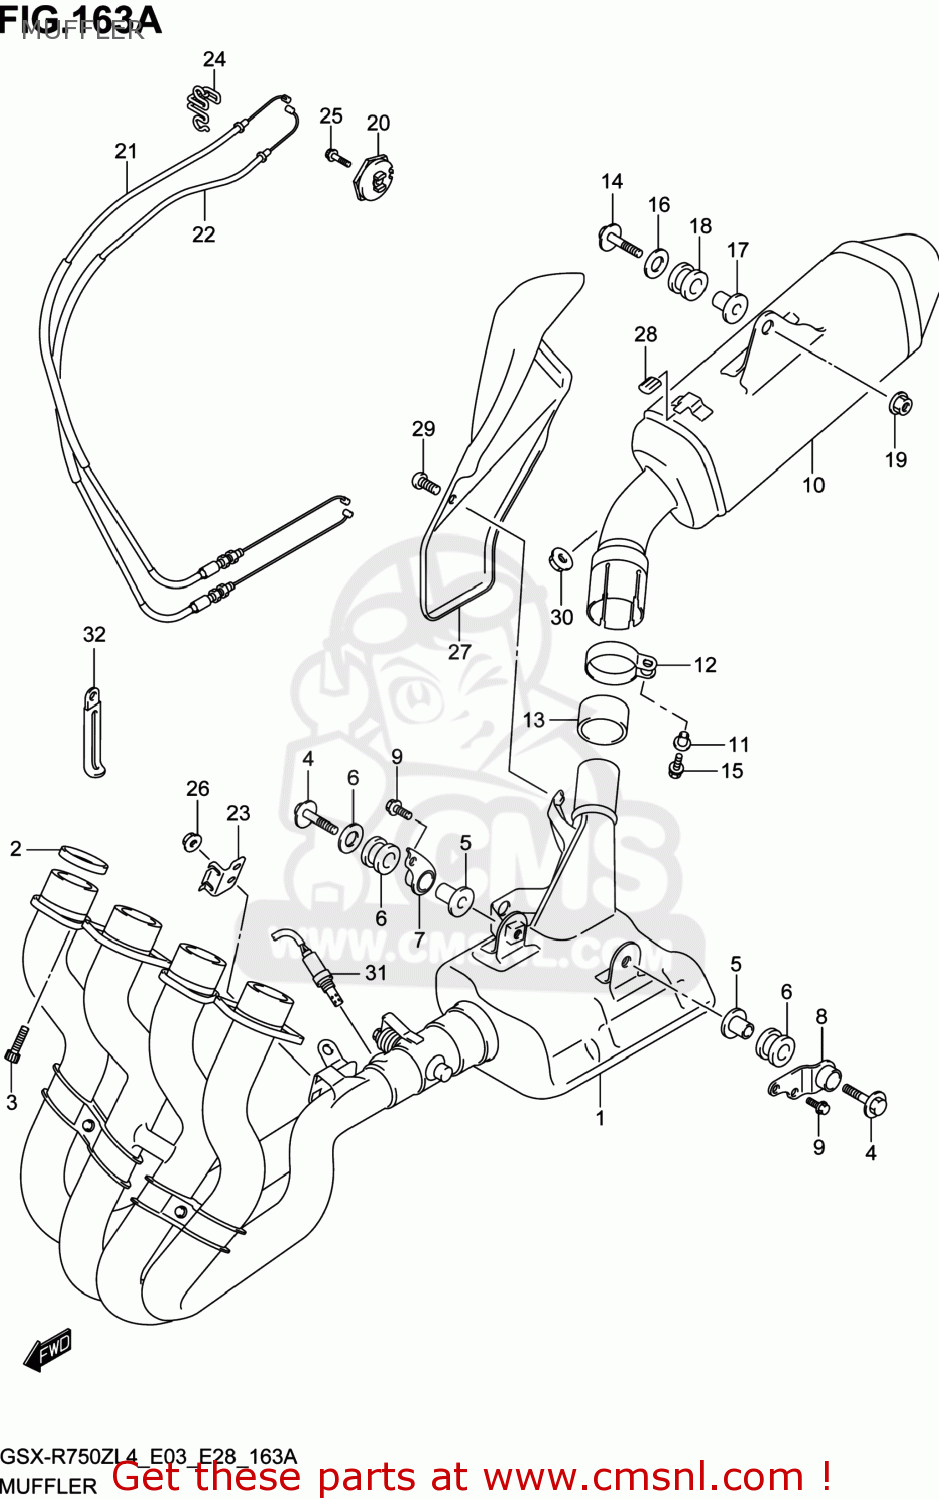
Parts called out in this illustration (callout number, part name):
1	EXHAUST
2	GASKET,EXHAUST PIPE
3	BOLT(8X25)
4	BOLT(8X45)
5	SPACER(8.6X12X24.2)
6	CUSHION
7	BRACKET,CHAMBER SPRT,R
8	BRACKET,CHAMBER SPRT,L
9	BOLT
10	BODY,MUFFLER
11	SPACER,MUF CLAMP
12	CLAMP,MUFFLER CONNECTOR
13	CONNECTOR,MUFFLER
14	BOLT(8X45)
15	BOLT(8X40)
16	WASHER(8.5X28X1.5)
17	SPACER(8.6X12X24.2)
18	CUSHION
19	NUT
20	PULLEY,CONTROLLER
21	CABLE,EXHAUST VALVE NO.1
22	CABLE,EXHAUST VALVE NO.2
23	BRACKET,EXHAUST VALVE CABLE
24	GUIDE,EXHAUST VALVE CABLE
25	BOLT
26	NUT
27	COVER,MUFFLER FR
28	GROMMET
29	SCREW(6X10)
30	CUSHION
31	SENSOR,OXYGEN
32	CLAMP(L:45)
